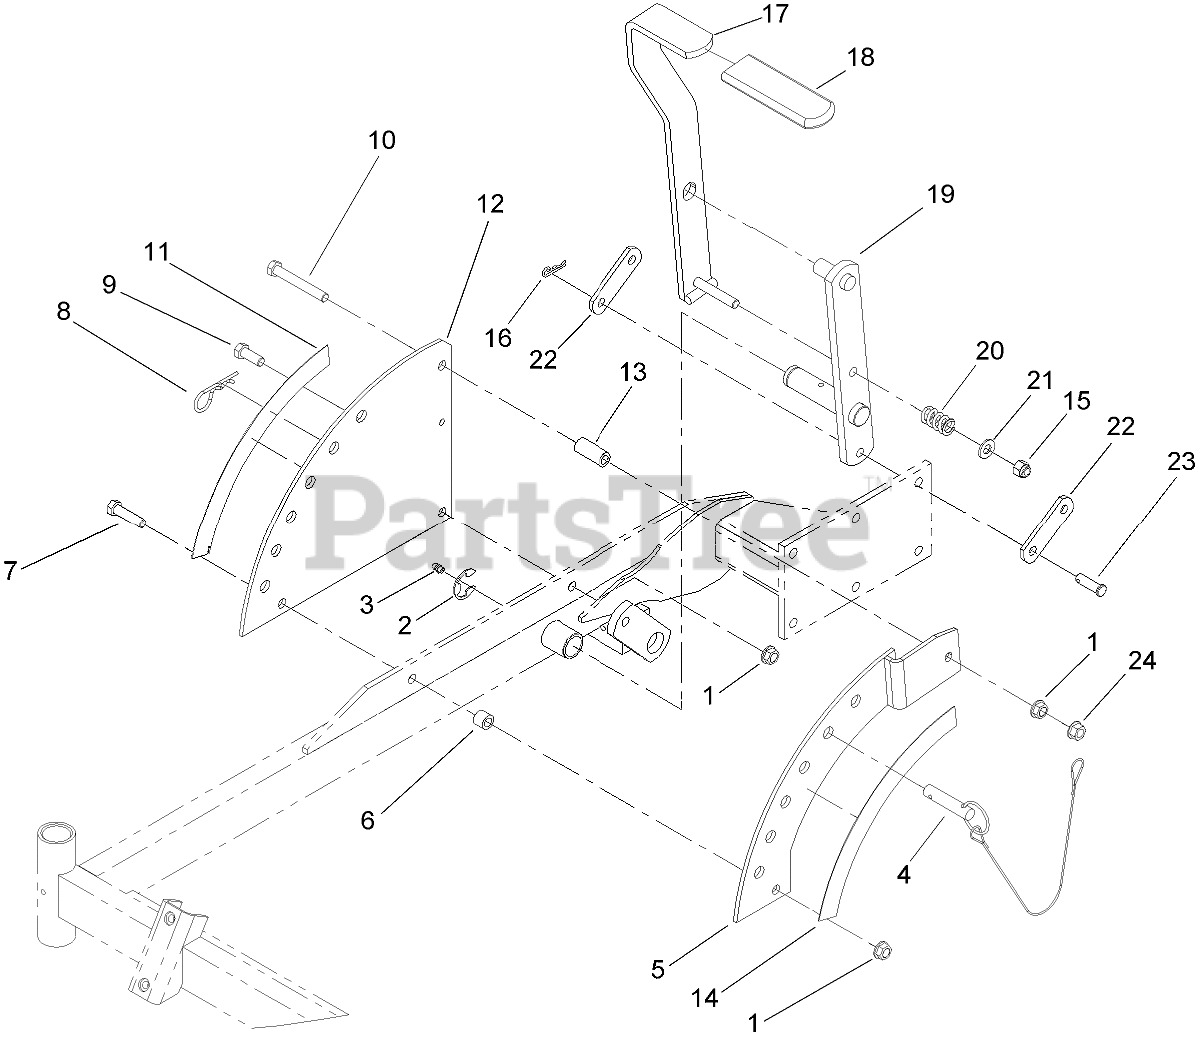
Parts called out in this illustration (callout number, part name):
1	NUT-HHF, WHIZ
2	WASHER-FLAT
3	FITTING-GREASE
4	PIN-HITCH
5	PLATE-LIFT
6	BUSHING-LEVER, LIFT
7	SCREW-HH
8	PIN-COTTER
9	SCREW-HH
10	SCREW-HH
11	DECAL-DECK HEIGHT, OUTER
12	PLATE-DECK LIFT
13	BUSHING-LEVER, LIFT
14	DECAL-DECK HEIGHT, INNER
15	NUT-LOCK, NI
16	PIN-COTTER
17	LEVER-LIFT
18	GRIP-LEVER, LIFT
19	ARM-DECK, LIFT
20	SPRING-COMPRESSION
21	WASHER-FLAT
22	ARM-LIFT, DECK
23	PIN-CLEVIS
24	NUT-HF
